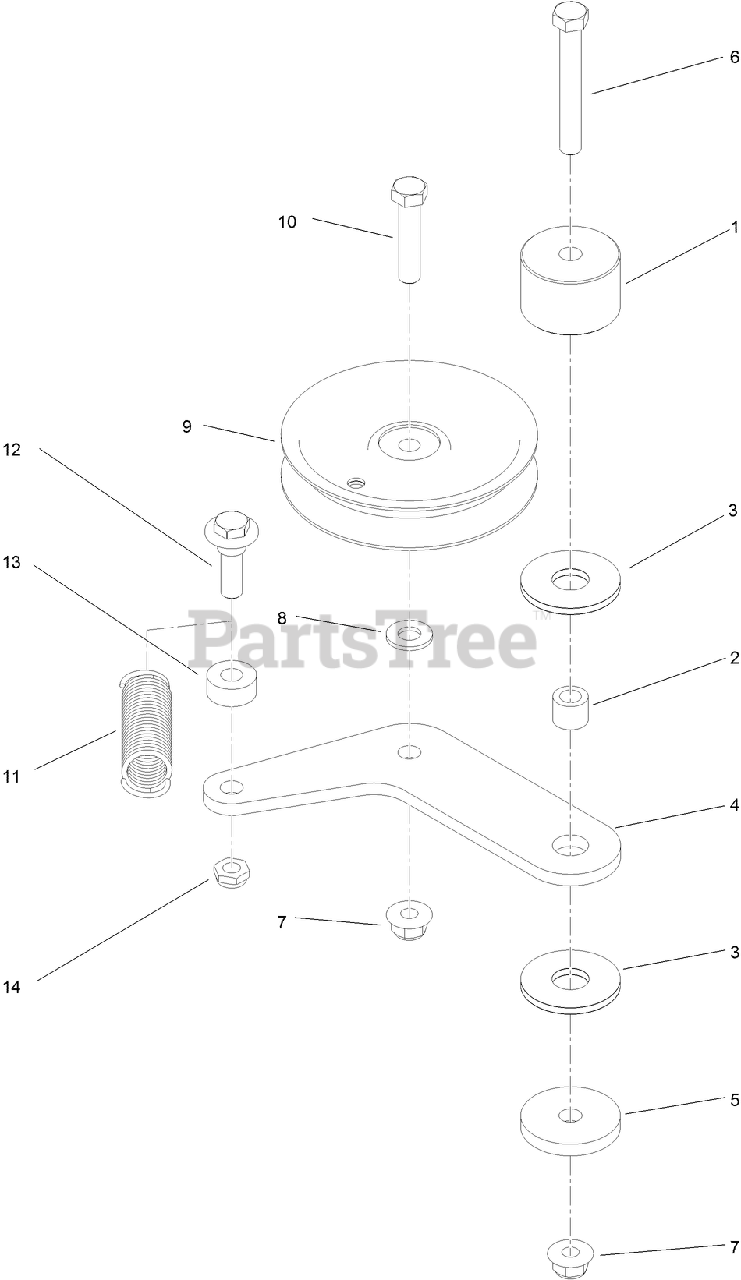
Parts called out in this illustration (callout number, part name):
1	HUB, IDLER
2	BUSHING-LEVER, LIFT
3	WASHER-FRICTION, COMPOSITE
4	PLATE-IDLER
5	WASHER-PLAIN
6	SCREW-HH
7	NUT-HF, NI
8	WASHER-FLAT
9	PULLEY-IDLER
10	SCREW-HH
11	SPRING-EXTENSION
12	SCREW-SHOULDER, HWH
13	SPACER
14	NUT-LOCK, NI
